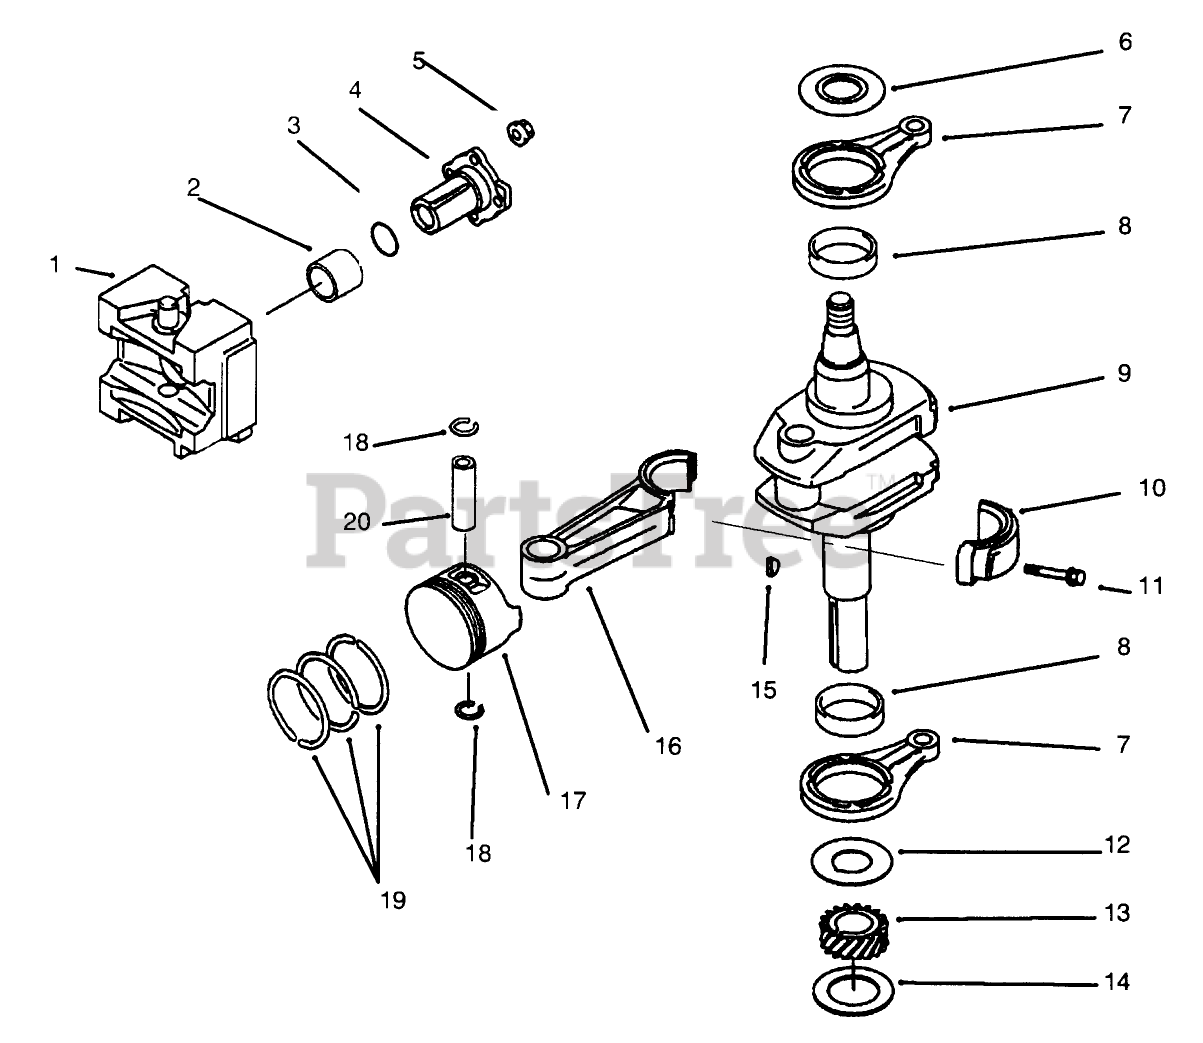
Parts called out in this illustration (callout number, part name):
1	Weight (Incl. Ref. # 2)
2	Bushing
3	O-Ring
4	Shaft
5	Nut
6	Spacer
7	Rod (Incl. Ref. #8)
8	Bearing
9	CrankshaftASM
10	Cap-Rod
11	Bolt
12	Spacer
13	Gear
14	Shim (1.18)
15	Key
16	Rod-Assy. Connecting (Incl. Ref. #10 & 11)
17	Piston
18	Ring-Snap
19	Piston Ring Set
20	Pin-Piston
